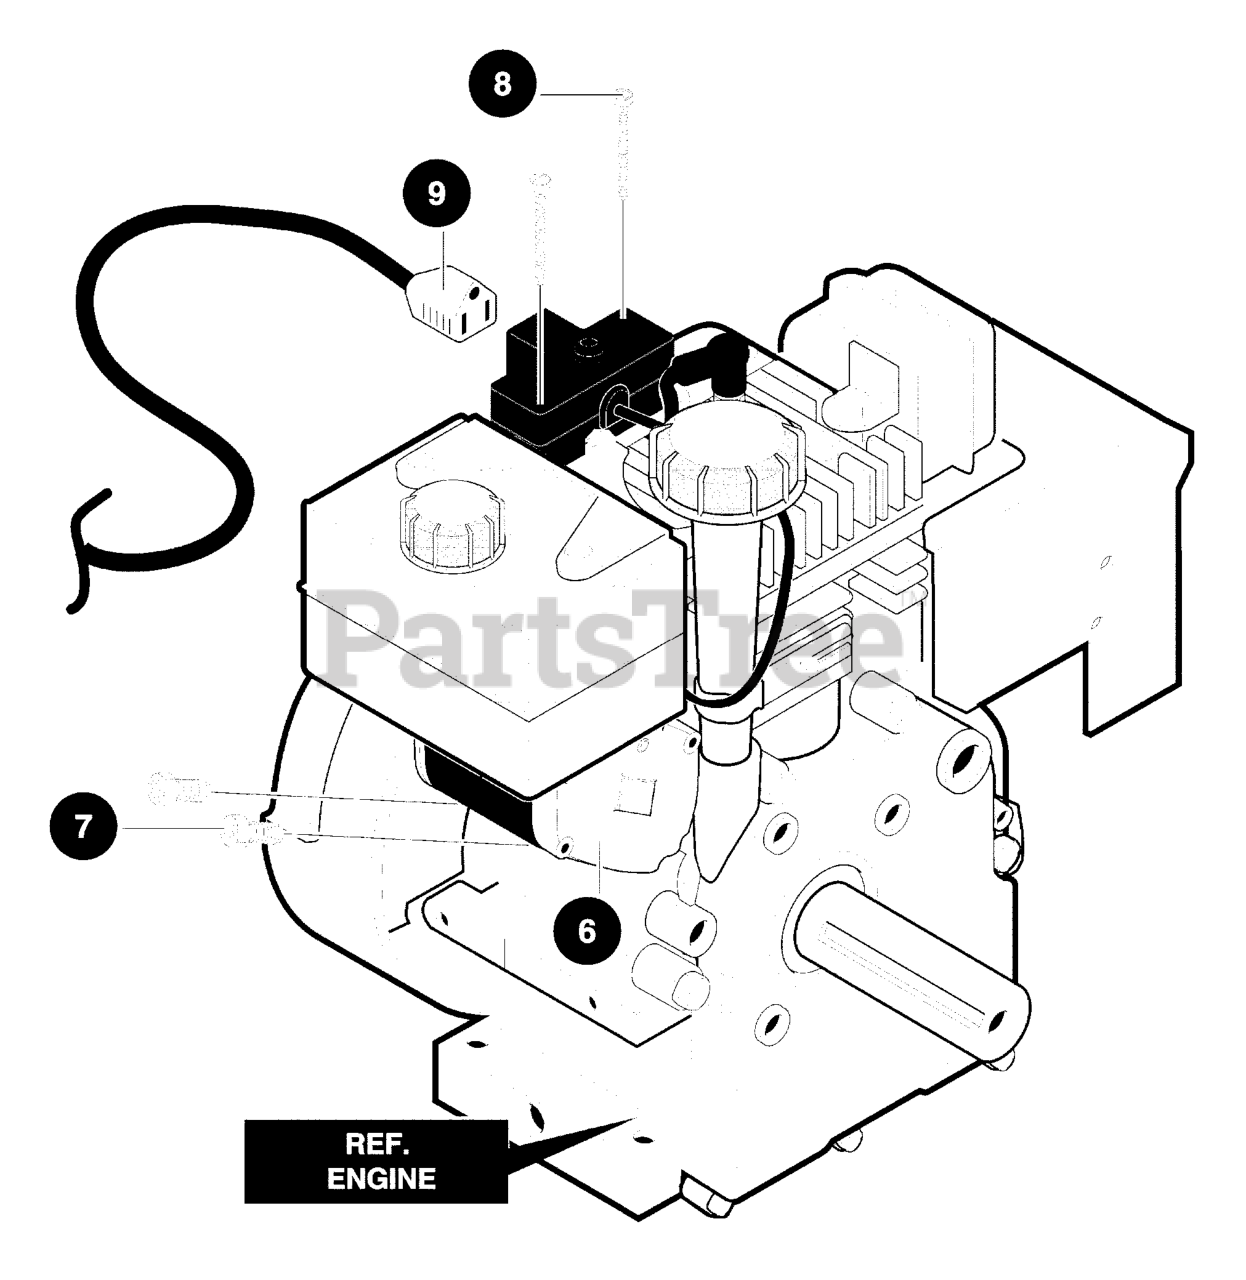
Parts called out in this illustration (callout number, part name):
6	MOTOR, STARTER
8	SCREW
9	CORD, Electric, 10FT. 110V
